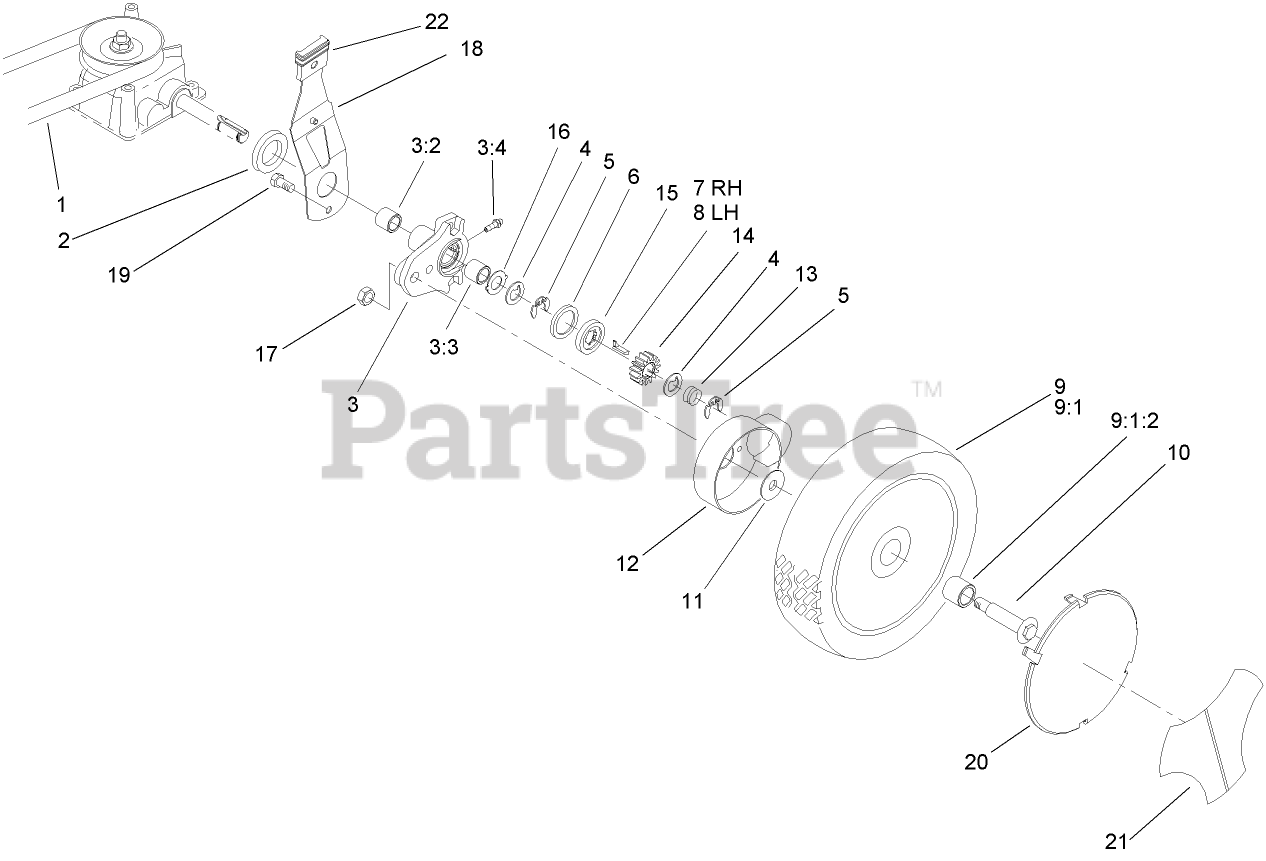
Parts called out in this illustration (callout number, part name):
1	V-BELT
2	SPACER-SHAFT, AXLE
3	REAR HEIGHT ADJUSTMENT ARM ASM
3:2	BUSHING
3:3	BUSHING
3:4	FITTING-GREASE
4	WASHER-THRUST, KEYED
5	RING-RETAINING,CLIP
6	RING-FRICTION
7	KEY-ROCKING, RH
8	KEY-ROCKING, LH
9	WHEEL AND TIRE ASM
9:1	Wheel ASM
9:1:2	BUSHING
10	BOLT-SHOULDER
11	WASHER-STEPPED
12	COVER-WHEEL
13	SPRING-COMPRESSION
14	GEAR-PINION
15	WASHER-CLUTCH
16	WASHER-ARM, PIVOT
17	LOCKNUT
18	REAR SPRING ARM ASM
19	SCREW-HWH
20	COVER-WHEEL, SMART
21	LABEL-WHEEL, SMART
22	KNOB-LEVER, HEIGHT ADJUSTMENT
